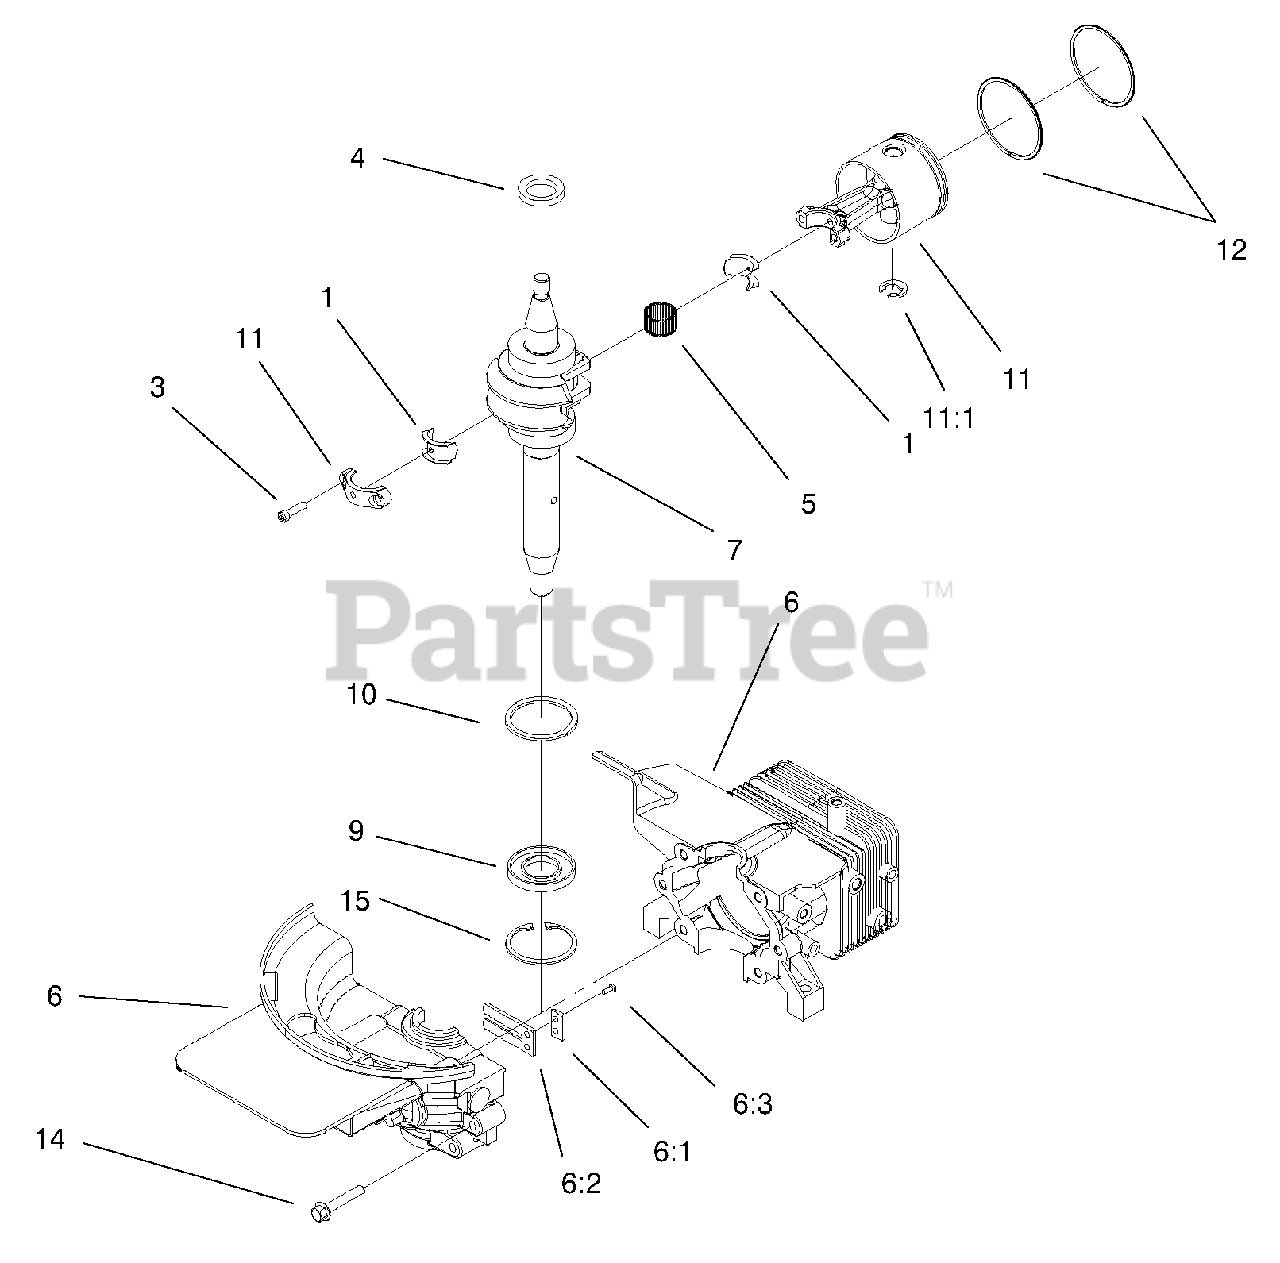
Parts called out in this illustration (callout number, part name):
1	Liner ASM
3	Screw-HSH
4	Seal-Oil
5	Bearing-Needle
6	Cylinder And Crankcase ASM
6:1	Plate-Backup, Reed
6:2	Reed-Carburetor
6:3	Screw-HH
7	Crankshaft And Bearing ASM
9	Seal-Oil
10	Ring-Retaining
11	Piston And Connecting Rod ASM
11:1	Ring-Retaining
15	Ring-Retaining
